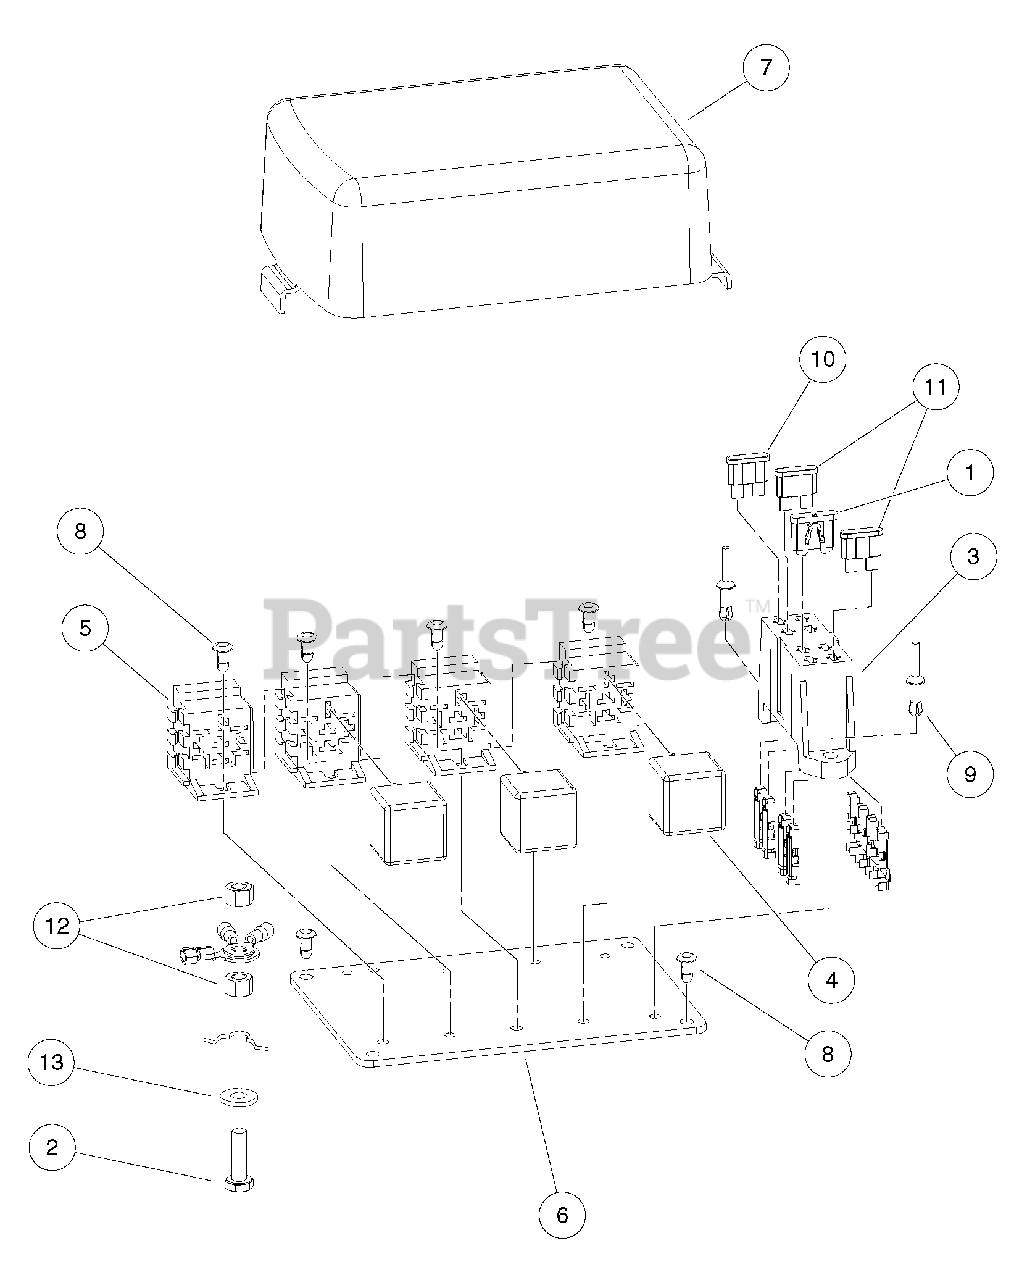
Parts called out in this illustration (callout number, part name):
1	Fuse, 10-Amp
2	Screw, 1/4-20 X .88 Hex Hd Cap
3	Fuse Block
4	Relay, Mini ISO, SPDT
5	Connector, Relay
6	Plate, Electrical
7	Cover, Electrical
8	Fastener, Push-in
9	Rivet, Drive
10	Fuse, 25-Amp
11	Fuse, 30-Amp
12	Locknut, 1/4-20 Dimpled
13	Washer, 1/4 Type A Narrow Flat
